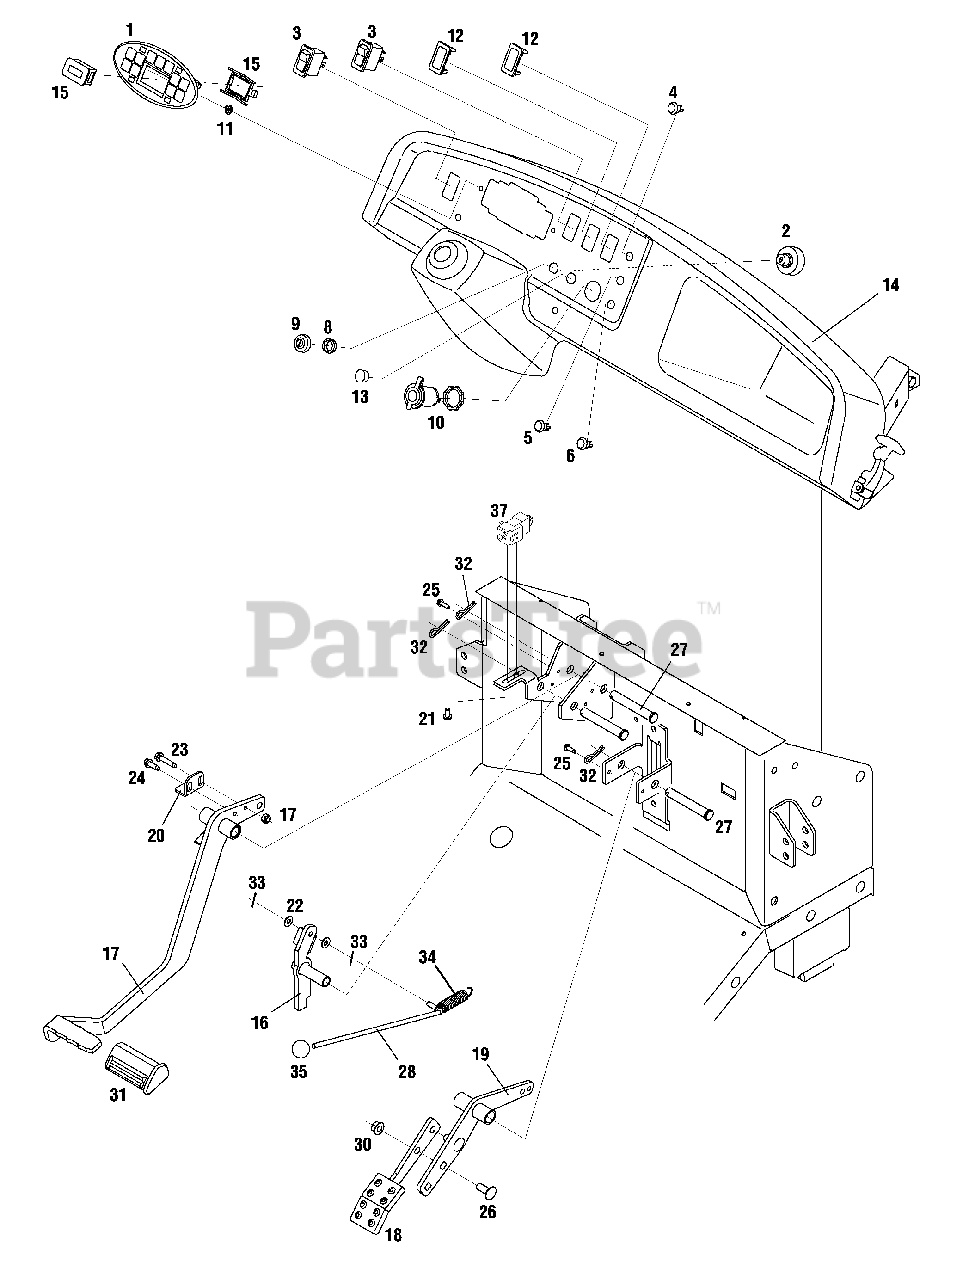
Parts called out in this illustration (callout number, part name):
1	Instrument Panel
2	Switch, Key
3	Rocker Switch
4	Switch, Green
5	Switch, Yellow
6	Switch, Red
7	Accessory Harness, Diff Lock
8	Nut, Ignition Switch, 5/8-32
9	Cap, Ignition Switch
10	Power Receptacle, 12V
11	Nut, Retainer, 1/8
13	Plug, Horn Switch
14	Dash Panel
15	Hour Meter w/ Retainer Clip
16	Lever , Parking Brake
17	Pedal Assembly, Brake
18	Pedal Assembly, Throttle
19	Pedal Arm Assembly, Throttle
20	Plate, Brake Switch
21	Screw, Hi-Lo, 1/4-20 x .5
22	Washer, Flat .25 x .630 x .0515
23	Screw, Self-tapping, 1/4-20x1.25
24	Screw, Self-tapping, 1/4-20, .75
25	Screw, Self-tapping, #10-32 x .625
26	Bolt, Carriage, 3/8-16 x 1.0
27	Pin, Clevis .50 x 3.25
28	Rod, Brake Lock
29	Nut, Hexlock, 1/4-20 GR 8
30	Nut, Flange Lock, 3/8-16
31	Pad, Brake Pedal
32	Pin, Cotter, .125 x 1.75
33	Pin, Cotter, 1/16
34	Spring, Extension, .637 x 2.972
35	Knob, Ball
36	Cover, Protective
37	Snap Mount Switch, Interlock
